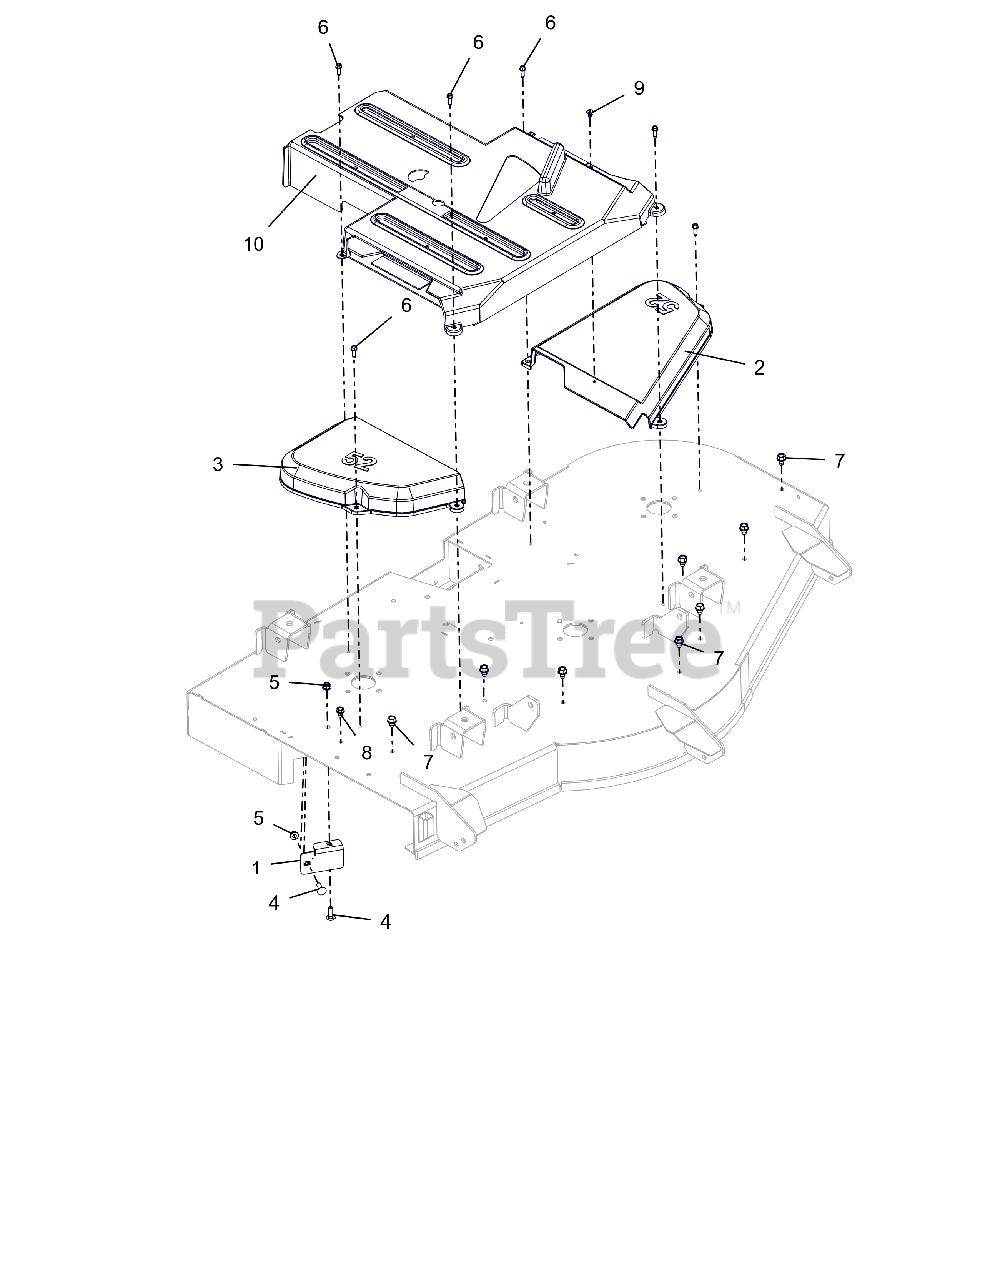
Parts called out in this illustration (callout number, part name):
1	STRIP, DEFLECTOR - 52"
2	COVER, BELT 52" LH
3	COVER, BELT 52" RIGHT
4	BLT,RHSN .31-18X1.00 G5 ZCC
5	NUT,LK-NYL-FLG .31-18 G5ZC120
6	SCR,TAP .25-20X.75 HWH TR ZCC
7	SCR,TAP .375-16X.50 HWH TR ZCC
8	SCR,TAP .312-18X.50 HWH TR ZCC
9	SCR-PAN .25-15X.50 6L H/LZB500
10	GUARD, CENTER, DECK
